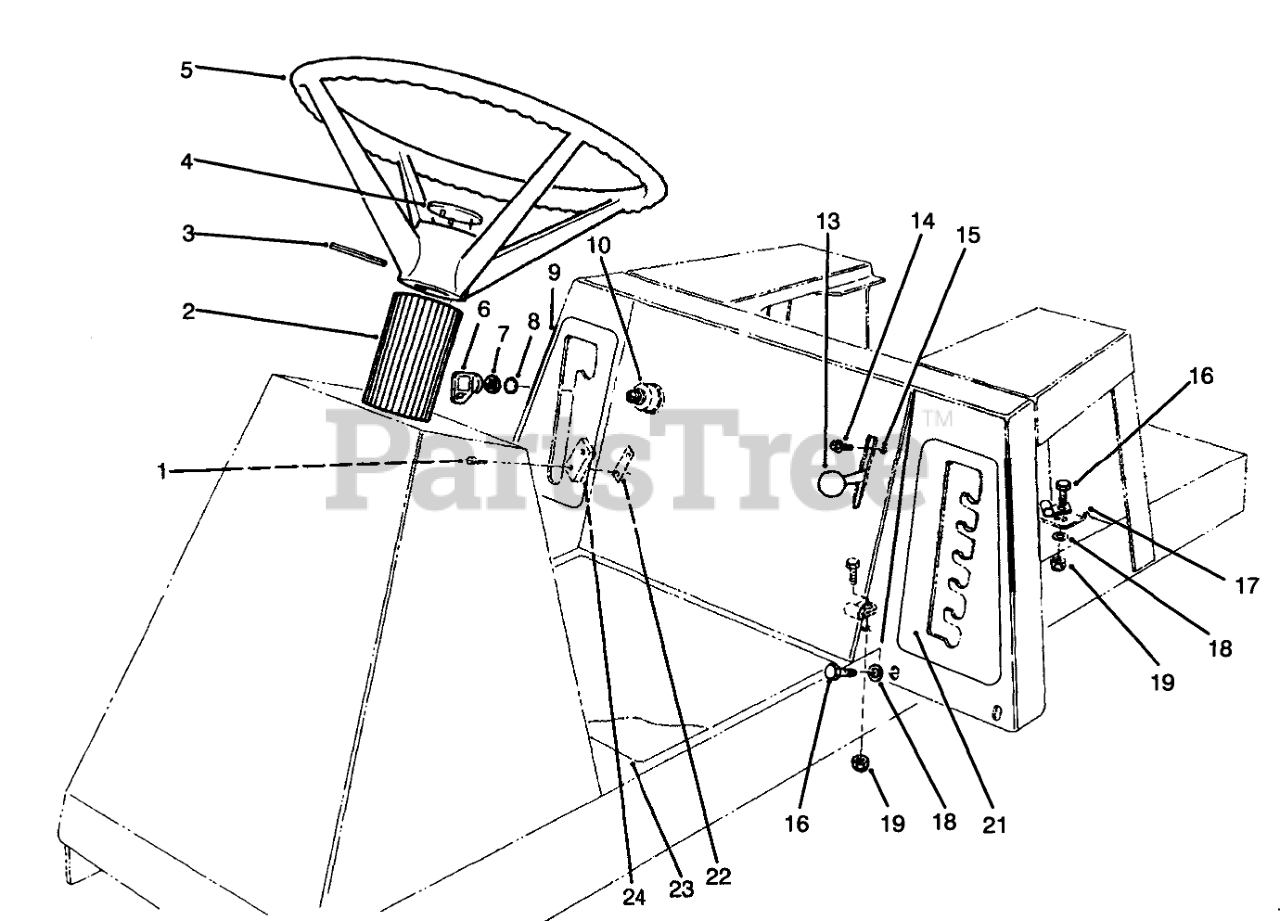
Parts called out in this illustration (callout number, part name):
1	SCREW-HH
2	COVER-STEERING SHAFT
3	PIN-ROLL
4	INSERT - STRG WHL F/W
5	Assy.-Wheel, Steering (Incl. Ref. #4)
6	KEY-IGNITION
7	NUT-HH
8	WASHER-TOOTH, INTERNAL
9	DECAL - DECK ENGAGE
10	Switch-Ignition (Incl. Ref. #6-8)
13	KNOB-CONTROL
14	SCREW-HWHTF
15	Control-Throttle (Incl. Ref. #13)
16	SCREW-HH
17	CLAMP
18	WASHER-PLAIN
19	NUT-LOCK, NI
21	DECAL - HOC
22	NUT-SPEED
23	INSTRUCTION DECAL
24	SWITCH-MICRO
